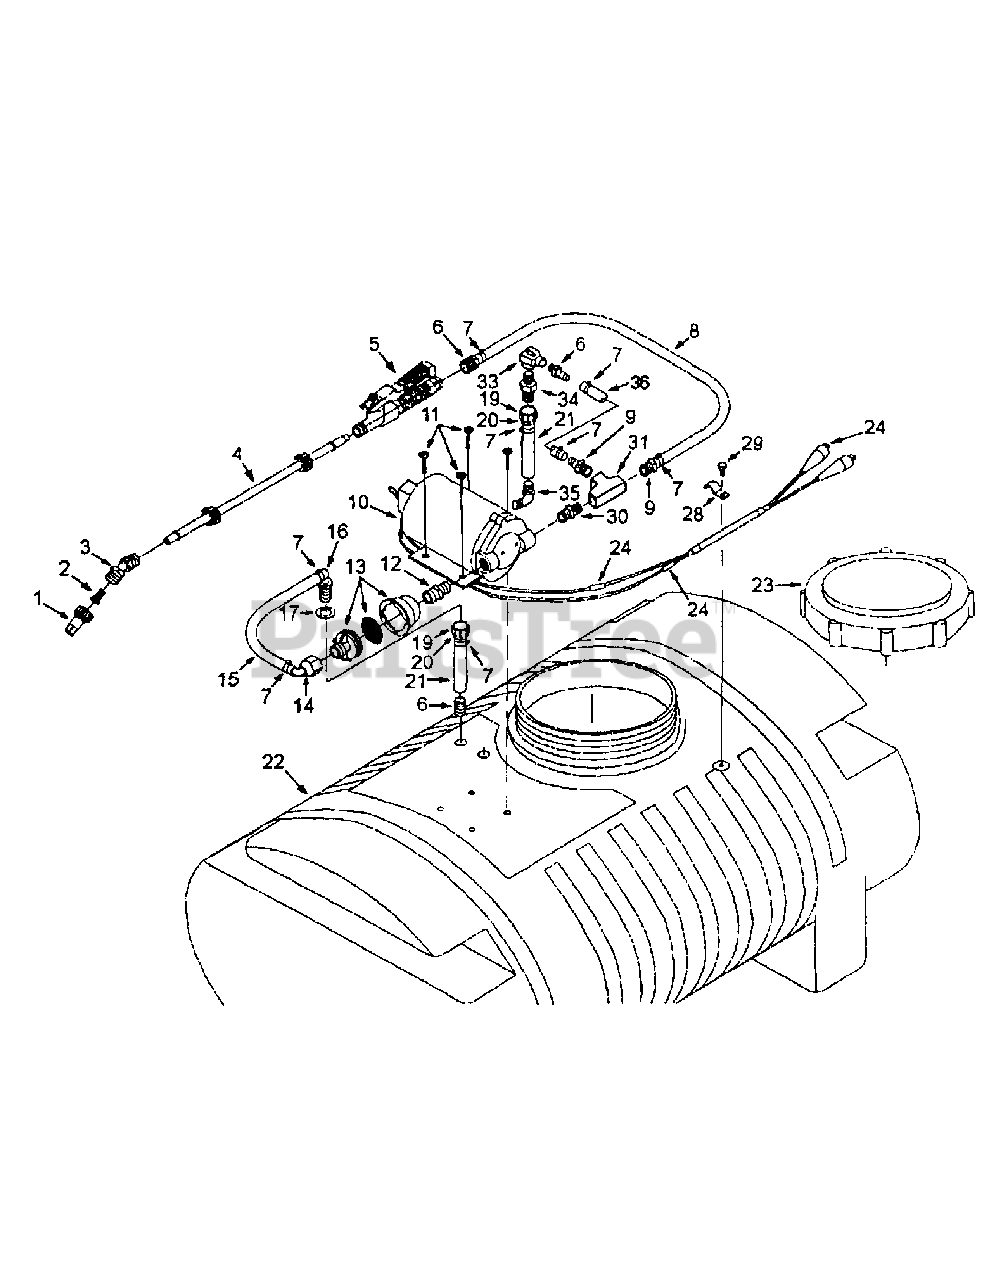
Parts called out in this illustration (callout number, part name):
1	Spray Tip, Adjustable
2	Strainer
3	Adapter, 45°.
4	Extension Wand, 15"
5	Trigger Valve
5	Wand Assembly
6	Hose Barb, 3/8 x 1/4 MPT
7	Hose Clamp
8	3/8 Hose, Reinforced PVC-25 ft.
8	Hose, 1/4" x 25', Flex Coil
9	Hose Barb, 3/8 x 3/8 MPT
10	Diaphragm Pump, Flojet
11	Mach. Screw, # 10-24 x 3/4 Pan Hd.
12	Fitting, Adapter
13	Filter, 30 Mesh S.S. Screen
14	Hose Barb, 3/8 x 90° Swivel Elbow
15	Hose, 3/8" x 18'
16	Hose Barb, 3/8" x 90° Male Elbow
17	Washer, 11/16 Nylon
19	Swivel Nut, Nylon
20	Hose Barb, 3/8 Nylon
21	Hose, 3/8" x 14'
22	Tank, 15 Gallon, Polyethylene
22	Tank, 25 Gallon, Polyethylene
23	Tank Lid
24	Wire Harness
28	Conduit Strap, 1/2
29	Cap Screw, 5/16-18 x 1/2 Hex Hd.
30	Nipple, 3/8 MPT Close
31	Tee, 3/8 FPT Brass
32	Hose Kit
33	Valve, 90°, 1/4 FPT
34	Fitting, Adapter, 1/4 MPT x 11/1 61
35	Elbow, 90°, 1/4 MPT x 3/8 Hose Barb
36	Hose, 3/8" x 5" PVC
